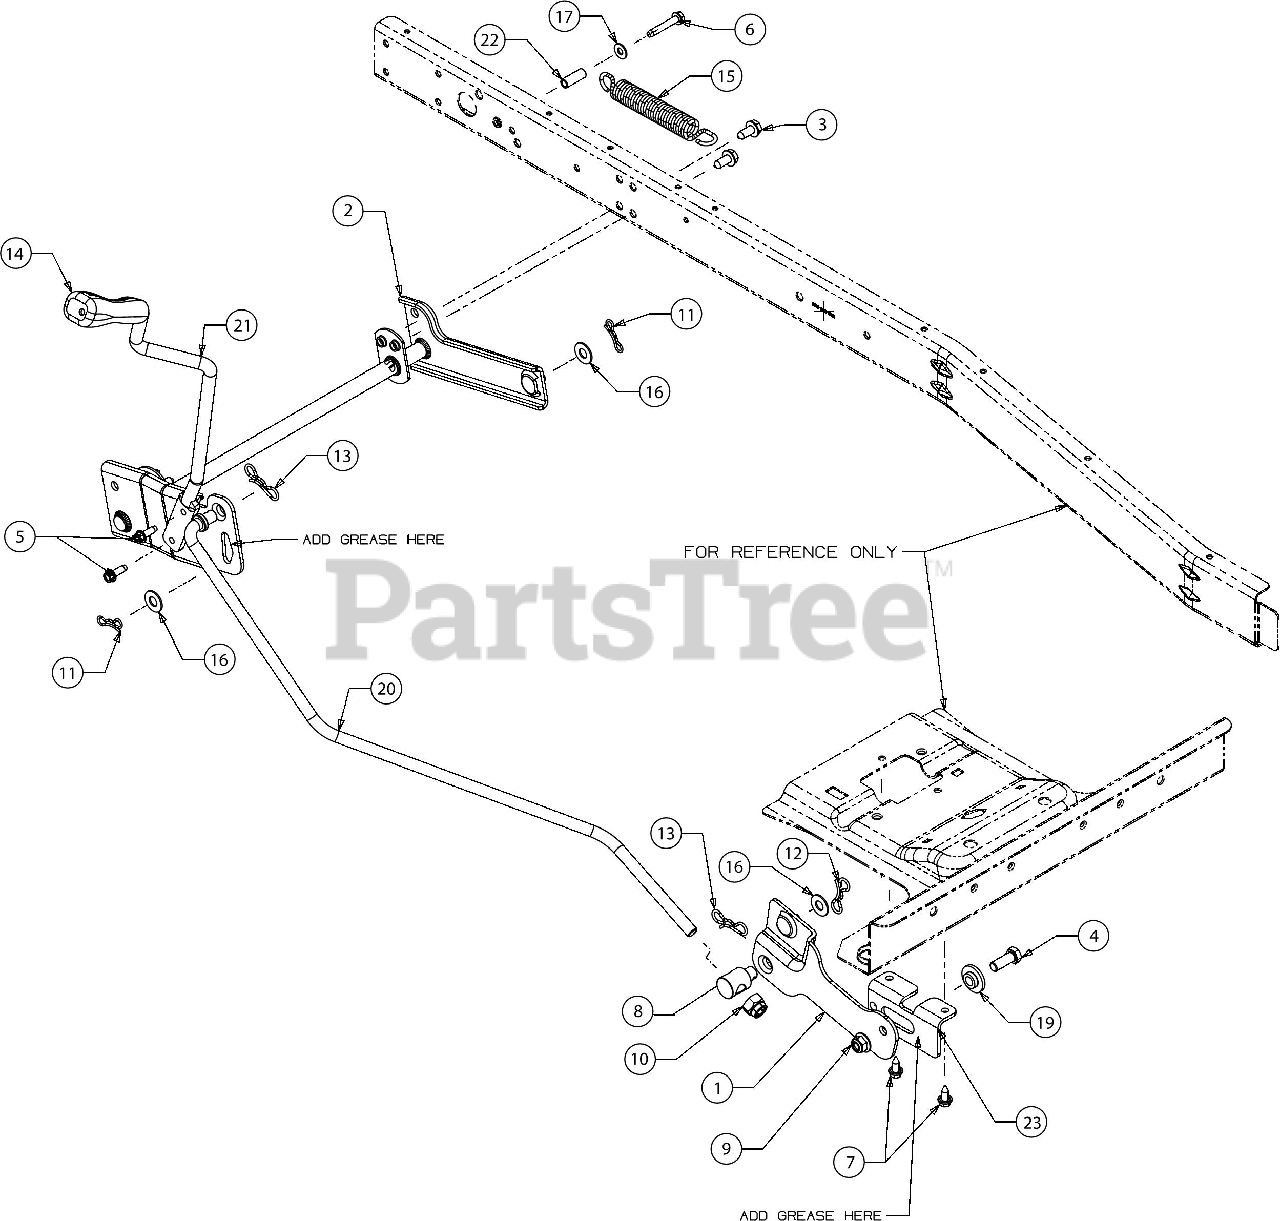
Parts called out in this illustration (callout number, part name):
1	BRACKET ASSEMBLY
2	LIFT SHAFT ASSEMBLY
3	SCREW 5/16-18 x .750
4	SCREW 3/8-16 x 1 GR5
5	SCREW 1/4-20 x .750
6	SCREW 1/4-20 x 1.50"
7	SCREW 1/4-20X.625
11	BOW TIE COTTER PIN 1/4-5/16
12	PIN:COTTER
13	BOW TIE COTTER PIN
14	HANDLE GRIP
15	EXTENSION SPRING .85 x 5.91
16	FLAT WASHER
17	FLAT WASHER
19	SHOULDER SPACER
21	DECK LIFT ROD
